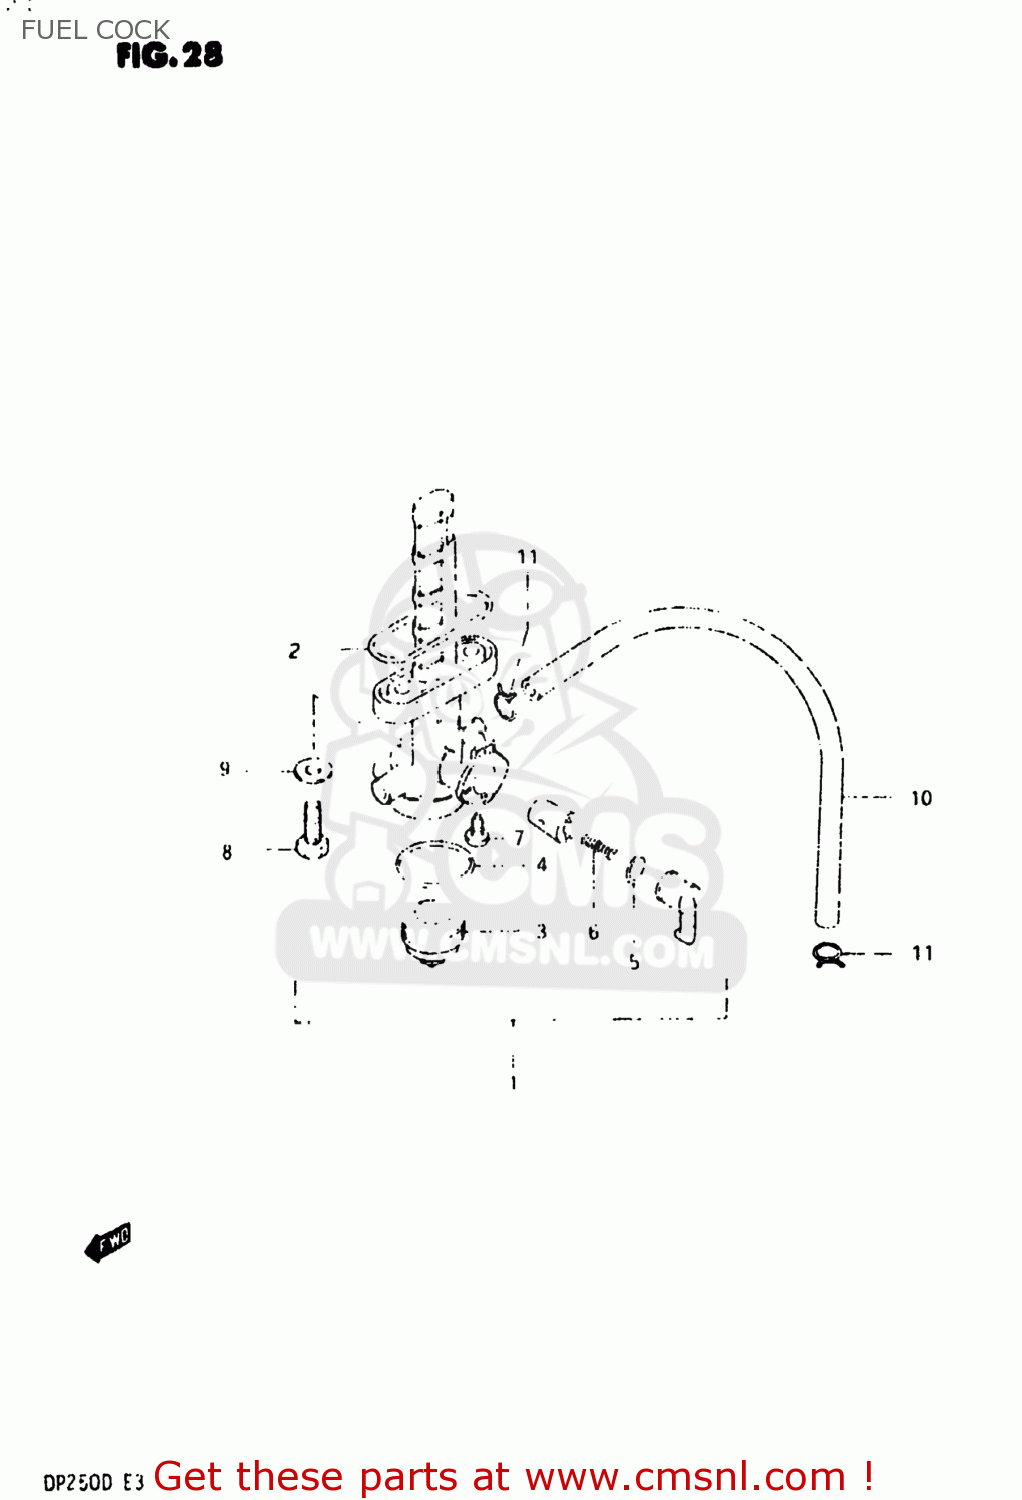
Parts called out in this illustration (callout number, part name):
1	COCK ASSEMBLY,FUEL
2	O RING,FUEL COCK
3	CUP,STRAINER
4	GASKET,FILTER (NAS)
5	O-RING
6	SPRING
7	SCREW
8	BOLT(6X20)
9	GASKET
10	HOSE
11	CLIP
